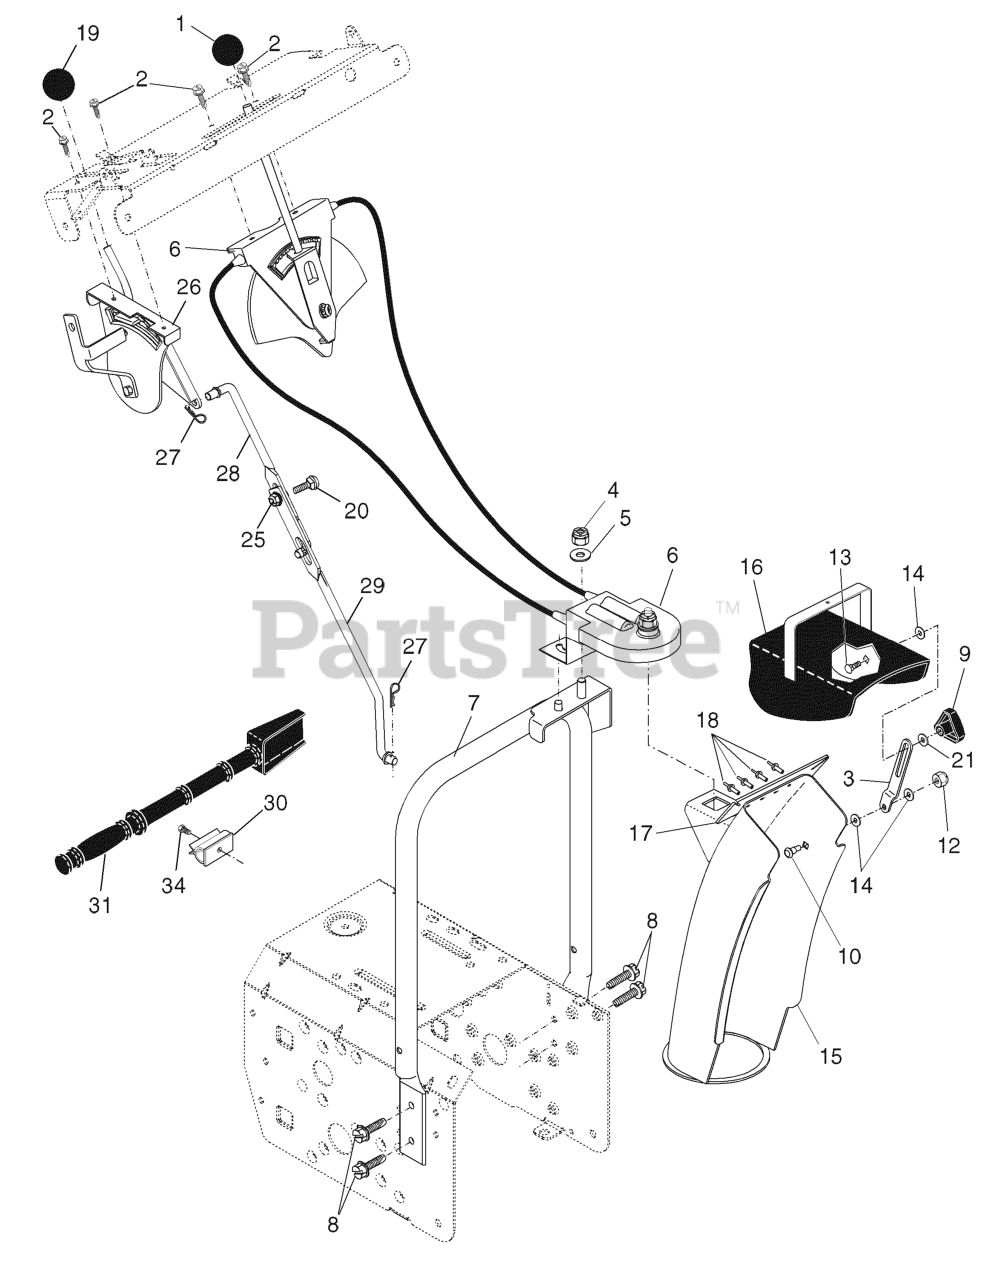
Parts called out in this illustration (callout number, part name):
1	RED KNOB SHIFTER
2	SCREW #10-24 X 5/8
3	STRAP, CHUTE
4	NUT
5	WASHER
6	CONTROL ASSEMBLY,CHUTE ROTATER
7	SUPPORT, PIVOT
8	SELF-TAPPING SCREW 5/16-18X3/4
9	KNOB, DEFLECTOR
10	SHOULDER BOLT
12	NUT.HEX.FLANGE.1/4
13	BOLT
14	WASHER, NYLON FRICTION
15	CHUTE ASSEMBLY
16	DEFLECTOR.WELDMENT.PNT.ORANGE
17	SEAL, DEFLECTOR
18	RIVET BLIND
19	KNOB LEVER, BLACK
20	BOLT
21	WASHER.20X8.5
25	NUT.FLANGE.5/16
26	HEAD ASSY SPEED
27	SPRING RETAINER
28	ROD, UPPER SPEED CONTROL
29	ROD, LOWER SPEED CONTROL.SNOW
30	CLIP.CLEANOUT.TOOL
31	CLEAN OUT TOOL
34	SCREW.HWH.13-16-5.8.BZP
